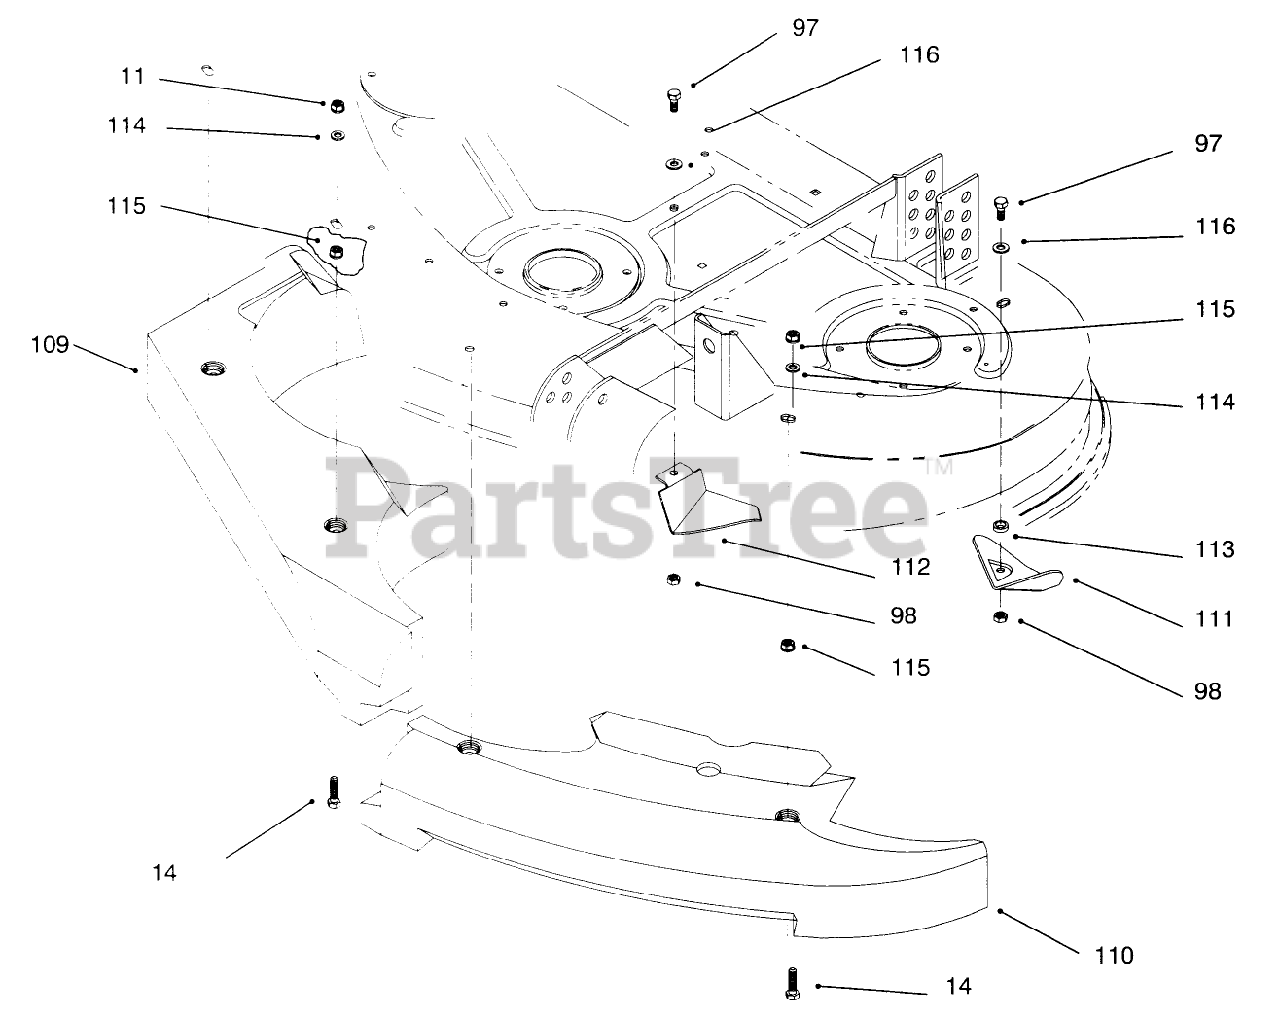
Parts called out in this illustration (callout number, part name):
14	SCREW-HH
97	SCREW-HH
98	NUT-LOCK, NI
109	BAFFLE-RH
110	BAFFLE-LH
111	PLATE-KICKER
112	KICKER-CENTER, REAR
113	SPACER
114	WASHER-BELLEVILLE
115	NUT-KEPS
116	WASHER-PLAIN
